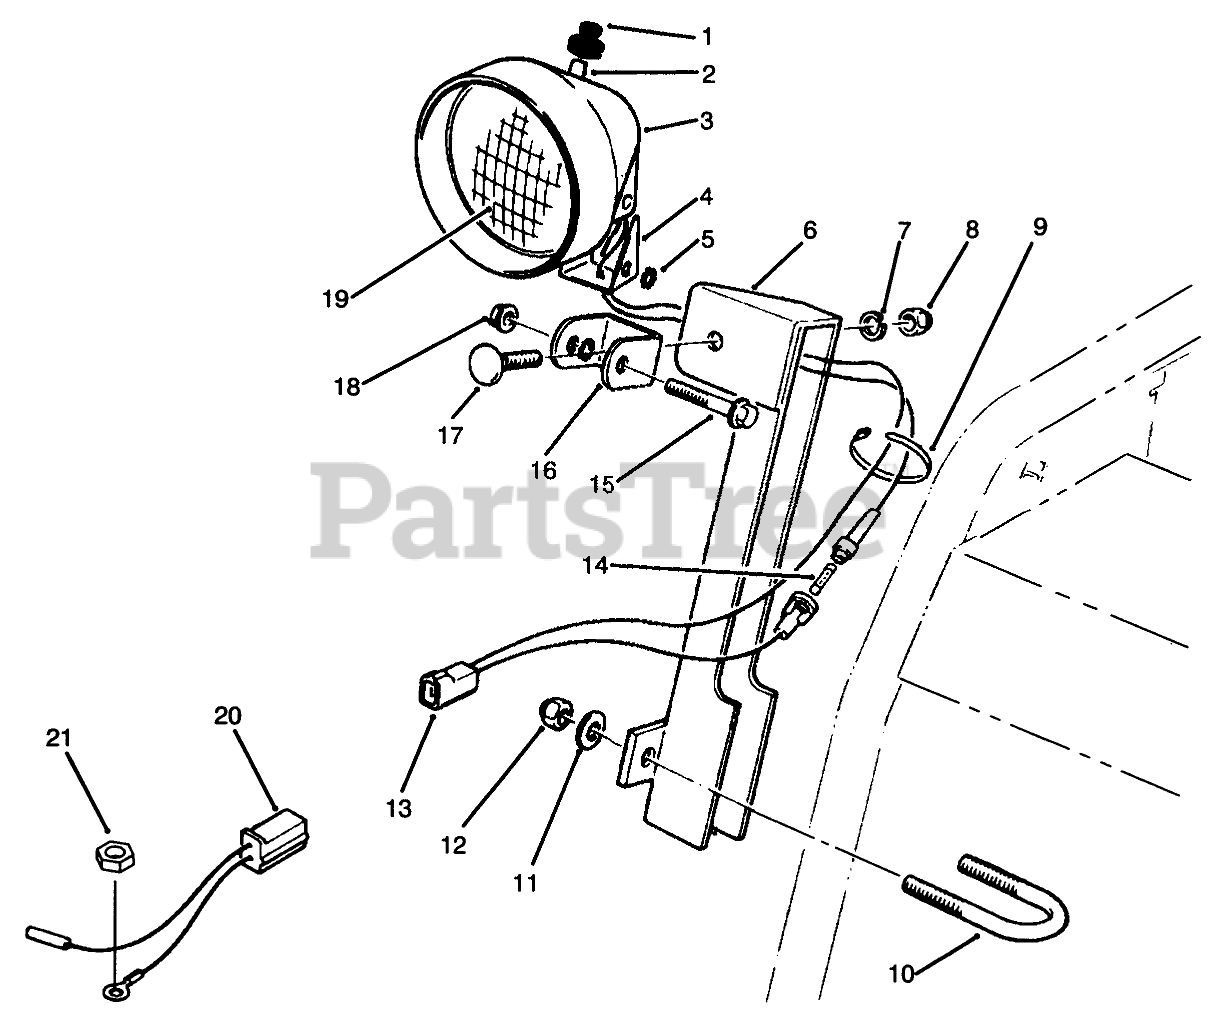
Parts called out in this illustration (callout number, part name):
1	BOOT-SWITCH
2	SWITCH ASM
3	Bucket-Headlamp
4	TO BE DISCONTINED-NOT NEEDED ON PRODUCT
5	WASHER-LOCK
6	Mount-Lamp
7	WASHER-LOCK
8	NUT-HEX
9	TIE-CABLE
10	U-BOLT
11	WASHER-PLAIN
12	NUT-LOCK, NI
13	Wire-Assembly
14	Fuse-7-1/2 Amp.
15	SCREW-HH
16	BRACKET
17	BOLT-CARR
18	NUT-HF
19	BEAM-SEALED
20	WIRE ASM
21	NUT-HEX
